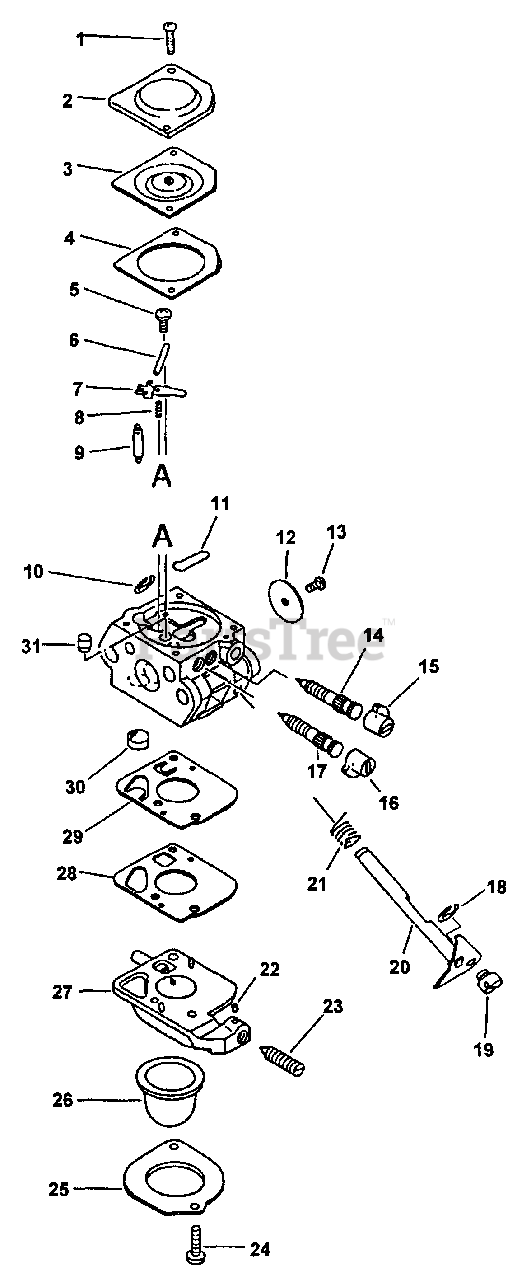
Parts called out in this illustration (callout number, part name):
2	COVER, METERING DIAPHRAGM
3	DIAPHRAGM, METERING
4	GASKET, METERING
6	PIN, METERING LEVER
7	LEVER, METERING
8	SPRING, METERING LEVER
9	VALVE, NEEDLE
11	PLUG, WELCH
12	VALVE, THROTTLE
14	NEEDLE, LOW SPEED
15	CAP, LIMITER - WHITE
16	CAP, LIMITER - RED
17	NEEDLE, HIGH SPEED
20	SHAFT, THROTTLE
21	SPRING, THROTTLE RETURN
22	PIECE, FRICTION
23	SCREW, IDLE ADJUST
25	RETAINER
26	BULB, PURGE
27	BODY ASSY, PURGE
30	STRAINER
31	NOZZLE, CHECK VALVE
